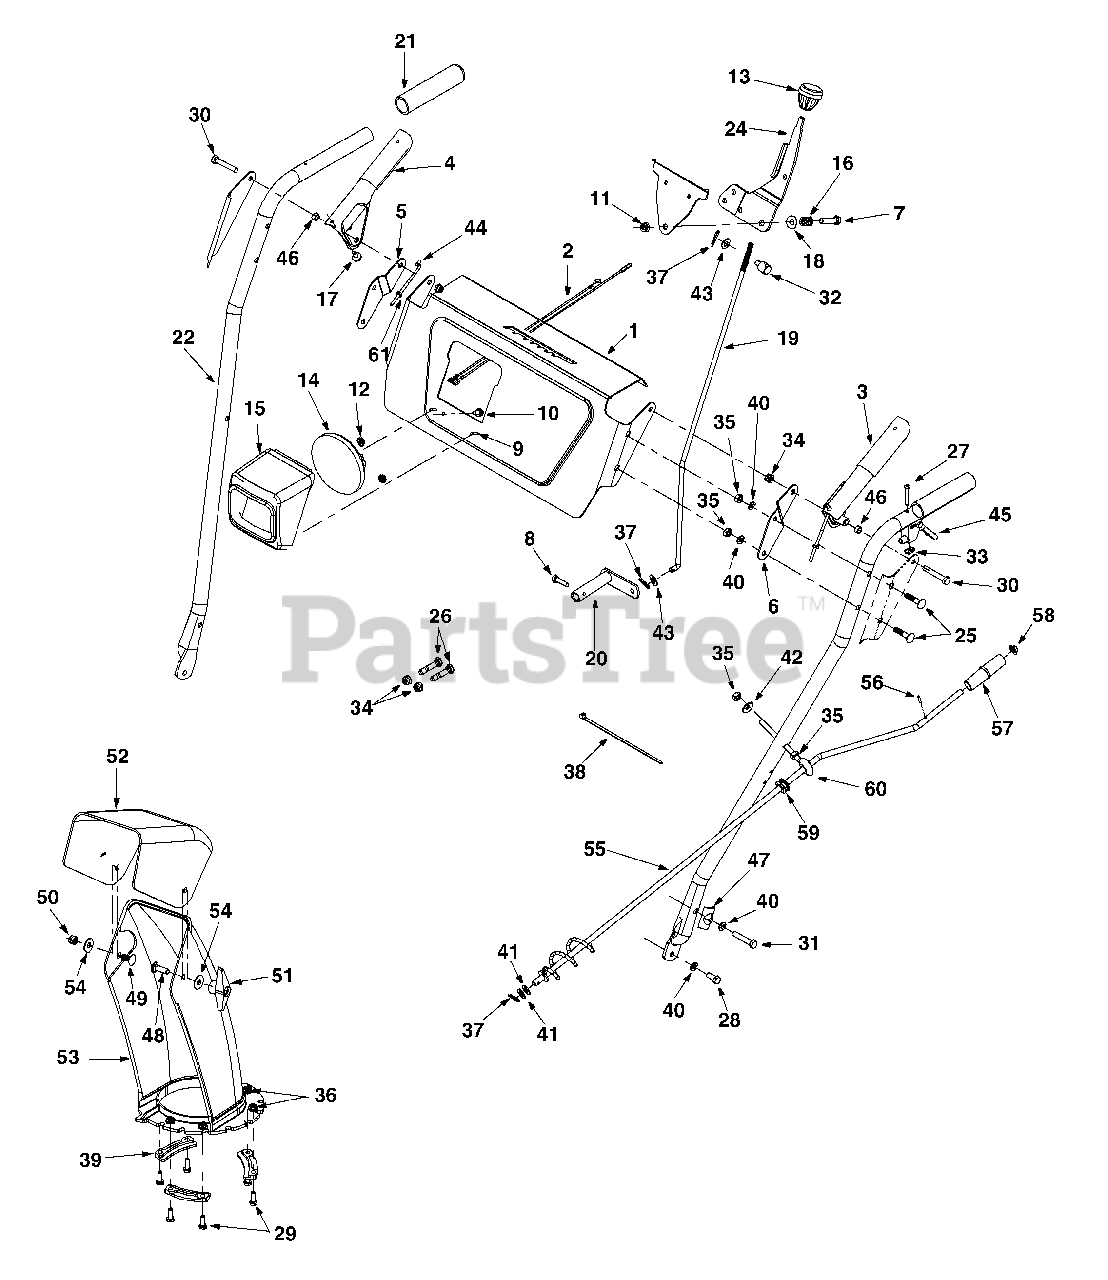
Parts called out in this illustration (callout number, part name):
3	Clutch Lever -L.H.
4	Clutch Lever -R.H.
8	Hex TT-Tap Scr. 1/4-20 x 1"
9	Hex B-Tap Scr. #10-16 x .62
10	Hex TT-Tap Scr. 1/4-20 x .6
11	Hex Jam Nut 3/8-24 Thd.
12	Self Threading Nut
13	Shift Knob
14	Headlight
15	Headlight Bezel
16	Compression Spring
17	Rubber Bumper
18	Bell-Wash. .4" I.D.
19	Shift Rod
26	Shear Bolt
27	Mach. Scr. #10-24 x 1.37
28	Hex Bolt 5/16-18 x .75" Lg.
29	Hex Bolt 1/4-20 x .75' Lg.
30	Hex Bolt 5/16-18 x 2" Lg.
31	Hex Bolt 5/16-18 x 1.75" Lg.
32	Ferrule
33	Flat Weld Nut #10-24 thd.
34	Hex L-Nut 5/16-18 Thd.
35	Hex Nut 5/16-18 Thd.
36	Hex L-Nut 1/4-20 Thd.
37	Hairpin Clip
38	Cable Tie
39	Chute Flange Keepers
40	L-Wash. 5/16" I.D.
41	Fl-Wash. .406" I.D.
42	Bell-Wash. .34' I.D.
43	Flat Wash. 5/16"
44	"Z" Fitting
45	Control Trigger
46	Spacer .325" I.D.
47	Handle Tab
48	Carriage Bolt
49	Carriage Bolt 5/16-18 x .75
50	Hex L-Nut 5/16-18 Thd.
51	Wing Nut Knob Ass'y.
52	Upper Chute
53	Lower Chute
54	Fl-Wash. .349 I.D.
55	Chute Crank Ass'y.
56	Roll Pin
57	Chute Crank Knob
58	Push Cap
59	Grommet
60	Eyebolt
61	Hex Jam Nut #10-24 Thd.
